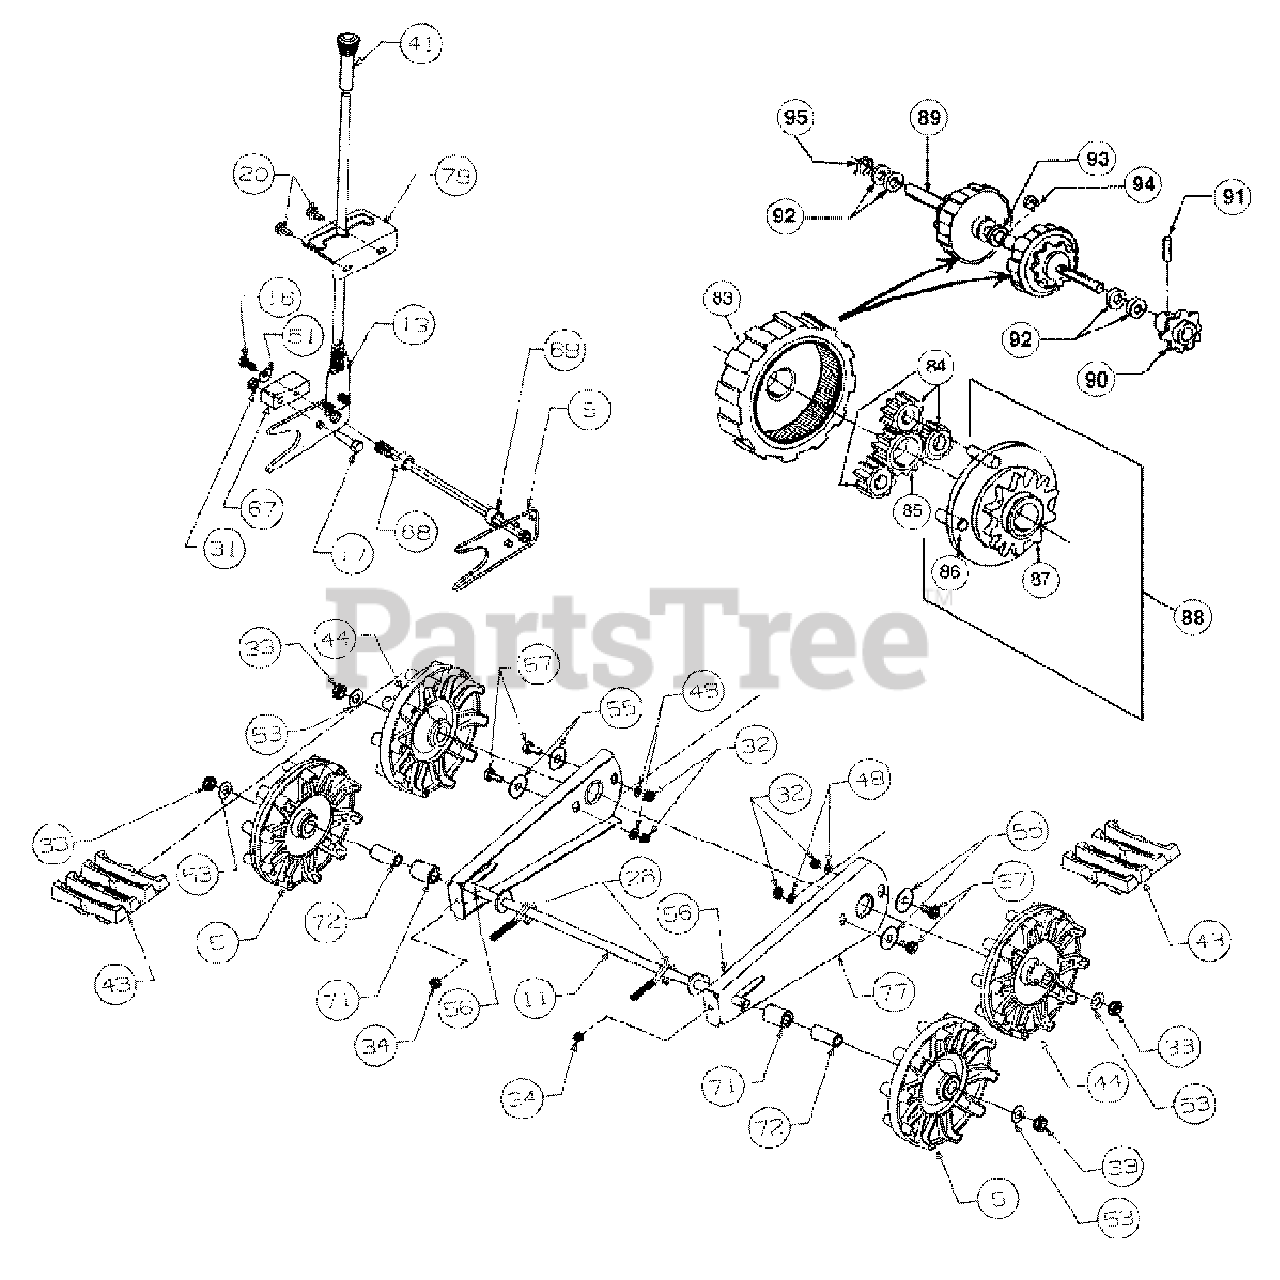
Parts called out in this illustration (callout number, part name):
5	Wheel Assembly Idler
11	Axle Assembly
16	Screw
26	Screw
31	Nut Lock
32	Nut Hex
33	Nut Jam
34	Nut Hex
43	Track
44	Wheel-Track Drive
48	Washer-Lock
51	Washer-Bell
53	Washer-Flat
55	Washer-Flat
56	Lubricant
57	Screw-Shoulder
67	Lift-Shaft Drive
68	Spacer
71	Spacer
72	Spacer
83	Gear Ring
84	Gear 12-Tooth
85	Gear 18-Tooth
86	Pin Dowel
87	Carrier
88	Carrier Assembly
89	Shaft-Track Drive
90	Sprocket-13 Tooth
91	Spring Pin 3/16" Dia. x 1" Lg.
92	Fl-Wash. .57" I.D. x 1.12" O.D.
93	Fl-Wash. 5/8" I.D. x 1" O.D.
94	Snap Ring .625" Shaft
95	Snap Ring .56" Shaft
